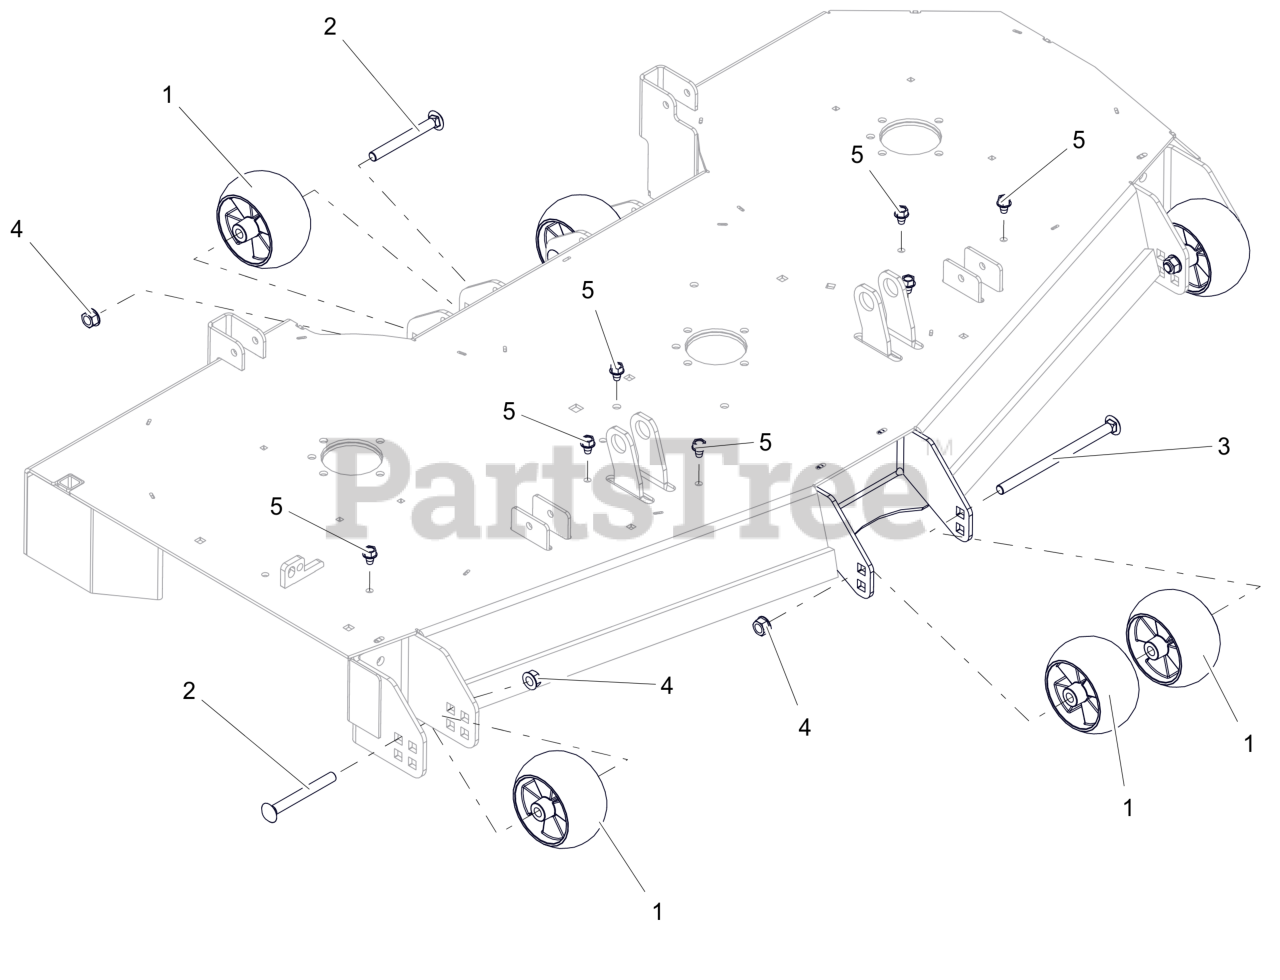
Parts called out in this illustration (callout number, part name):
1	WHEEL, ANTI SCALP - 5X3 CTR W/RIBS
2	BLT,RHNS .50-13X4.50 G5 ZCC NS
3	BLT,RHSN .50-13X8.00 G5 ZCC NS
4	NUT-LK-CTR-FLG .500-13 GG ZCC
5	SCR,TAP .375-16X.50 HWH TR ZCC
